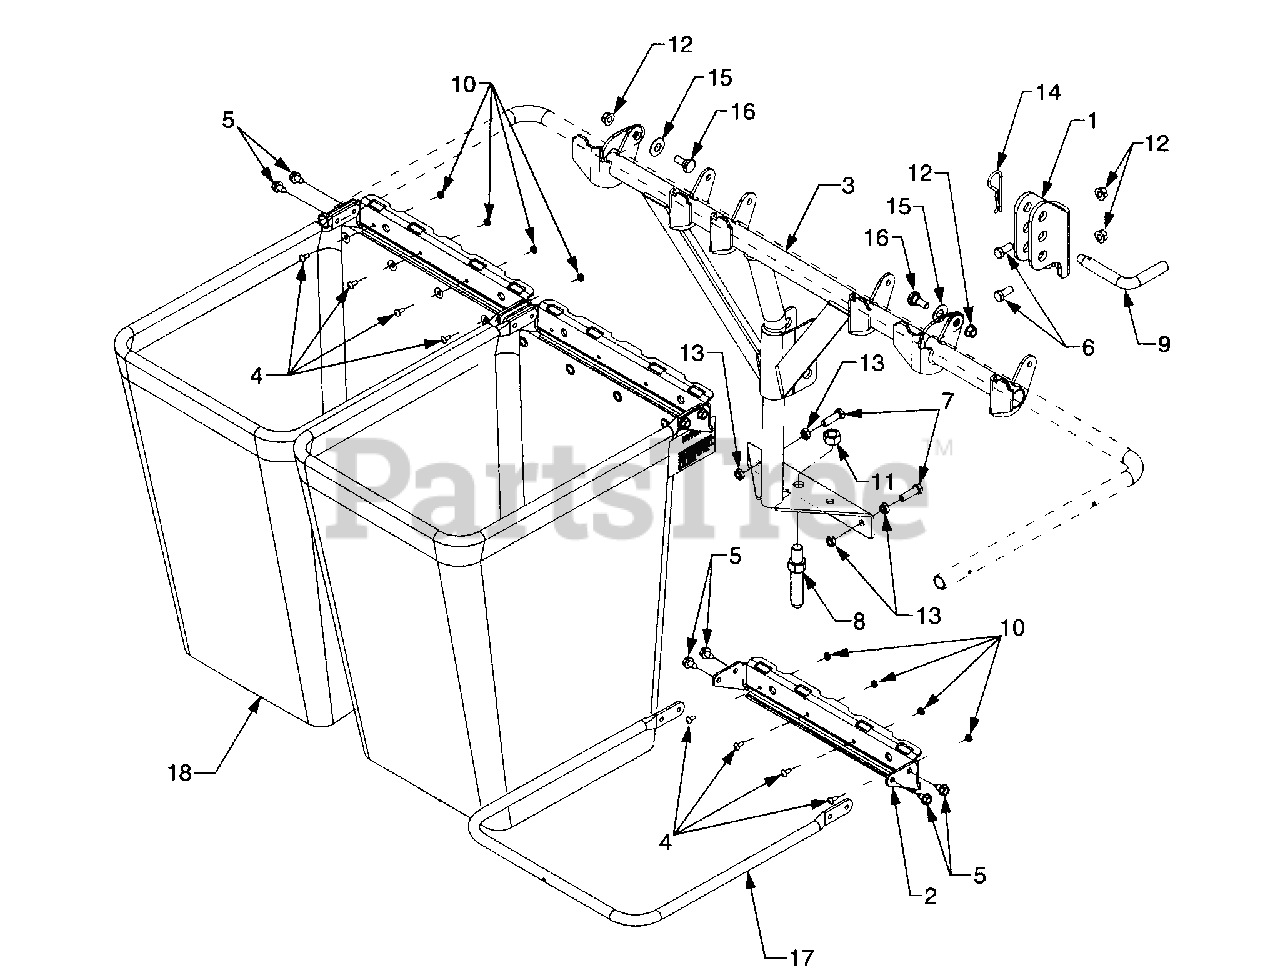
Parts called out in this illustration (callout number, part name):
1	Bracket, Hitch
2	Bracket, Bag Frame Hanger
3	Mounting Tube Assembly
4	Screw, Truss Hd. Mach. 10-24 x .5
5	Screw, Hex Wash. Hd. Tapp, 5/16-18 x .625
6	Screw, Hex Cap 3/8-16 x .880 GR5
7	Screw, Hex Cap 3/8-16 x 1.25 GR5
8	Stud, Adapter
9	Pin, Right Angle Clevis
10	Nut, Hex Sems, 10-24
11	Nut, Hex, 5/8-18 GR5.
12	Nut, Hex Flange Lock, 3/8-16
13	Nut, Hex Jam, 3/8-16 GR5
14	Pin, Internal
15	Washer, Belleville, .51 x 1.14 x .04
16	Screw, Shoulder .50 x .27: 3/8-16
17	Tube, Grass Bag Frame
18	Bag, Grass Catcher
